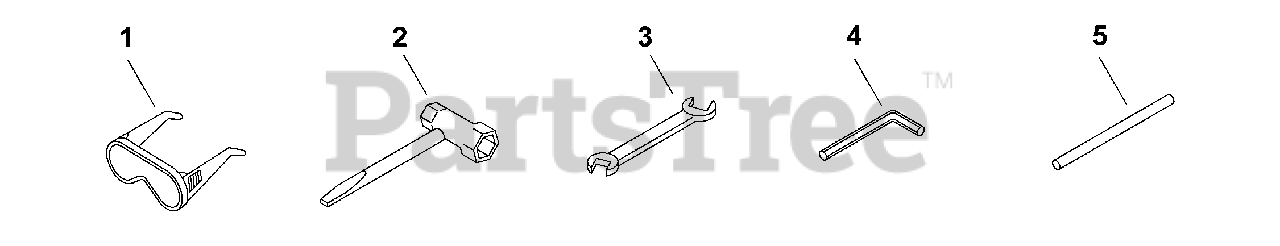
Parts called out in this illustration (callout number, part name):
1	GLASSES, SAFETY
2	T-WRENCH 17×19 L200
3	SPANNER 8×10
4	WRENCH, ALLEN 4 MM M5
5	TOOL, LOCKING 5×120 MM
